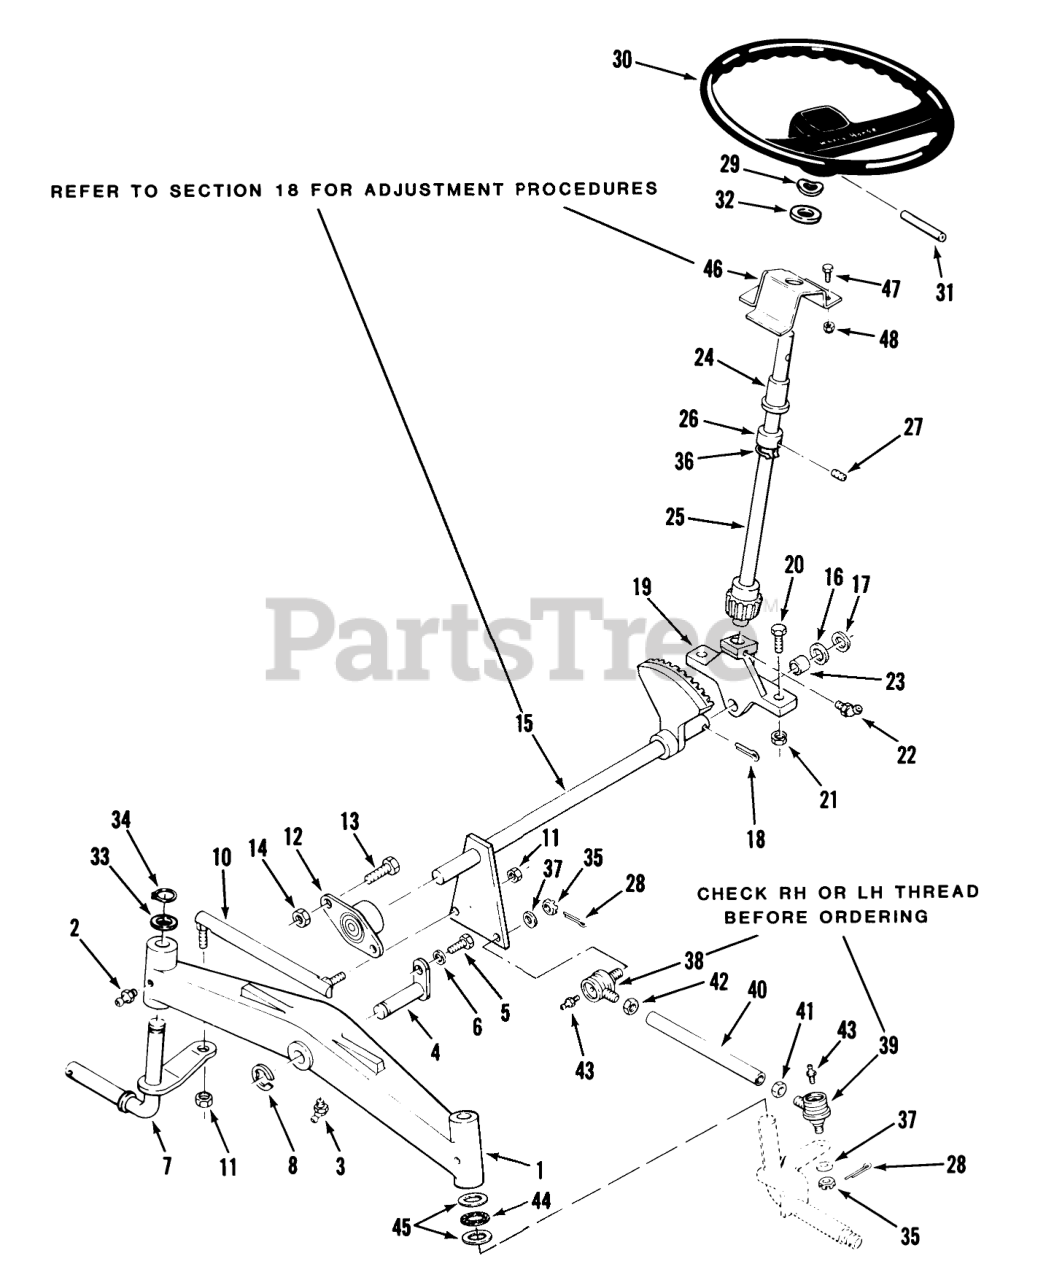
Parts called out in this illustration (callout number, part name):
1	AXLE-FRONT
1	Front Axle 520-HC
2	Zerk
3	FITTING-GREASE
4	PIN AND PLATE ASM
5	H H C S
6	Lockwasher
7	RH SPINDLE WA
7	Spindle
7	LH SPINDLE ASM
8	E-RING
10	Tie Rod RH
10	Tie Rod LH
11	E.S. Nut 3/8-24
12	BEARING-FLANGED
13	BOLT
14	NUT
15	ASS'Y-STRG SHAFT R
16	WASHER-SHIM
17	WASHER
18	PIN-4
19	Support
20	Bolt
21	NUT
22	FITTING-GREASE
23	BEARING-BRONZE
24	BEARING-FLANGED
25	Shaft-Upper Steering
26	Collar
27	SCREW-SET
28	Cotter Pin
29	WASHER-BOWED
30	STEERING WHEEL-13"
30	STEERING WHEEL-15"
31	Pin-Roll
32	WASHER-FLAT
33	WASHER
34	Snap Ring
36	RING-RETAINING
37	WASHER
38	SOCKET-BALLJOINT
39	SOCKET-BALLJOINT
40	Tube
41	NUT-HEX JAM 9/16-18
42	Nut
43	Grease Fitting
44	BEARING-THRUST
45	WASHER-THRUST
46	BRACKET-STEERING B
47	H H C S
48	Nut
